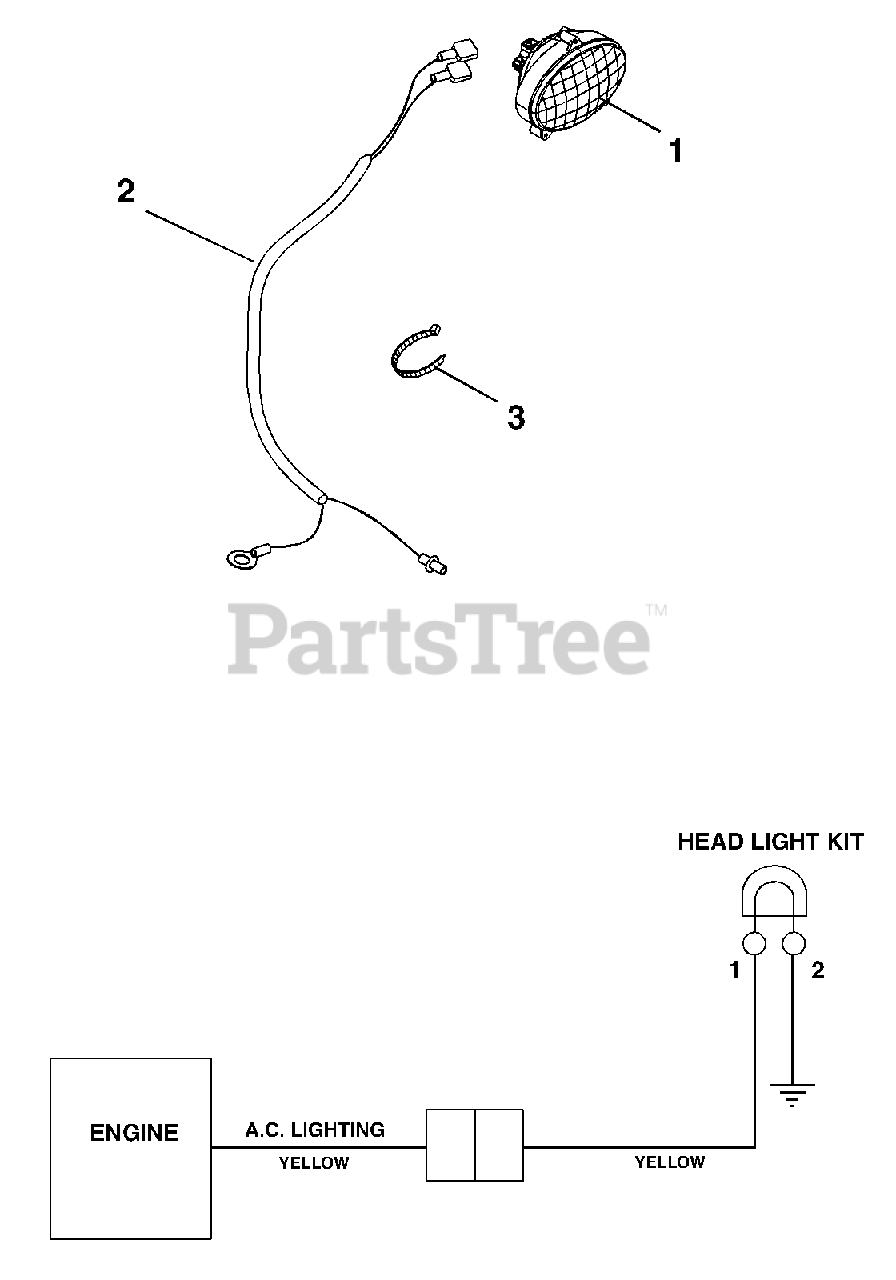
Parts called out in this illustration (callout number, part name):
1	HEADLAMP, OVAL W/ 1156 BULB
2	HARNESS, WIRE-LIGHT
3	CABLE TIE LG 5-1/2
